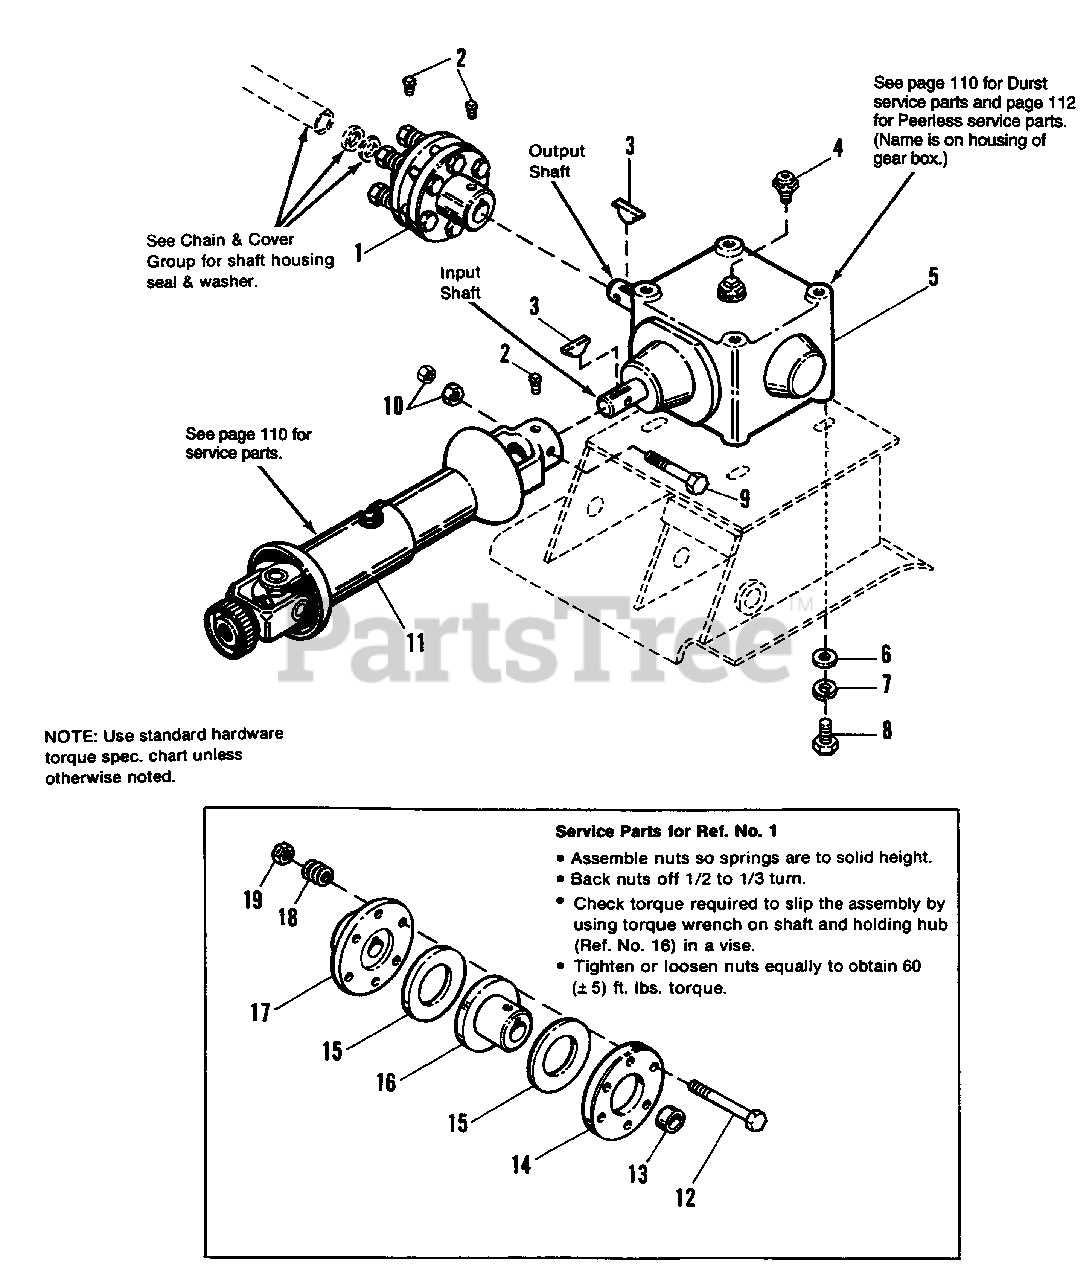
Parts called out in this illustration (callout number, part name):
1	TORQUE LIMITER ASSY.
2	SETSCREW, 5/16-18 x 3/4
3	KEY, Hi-Pro, 1/4 x 7/8
4	PLUG, Vent, 1/8-27 NPT
5	DRIVE ASSY., Right Angle
6	WASHER, Flat, 3/8 Std.
7	WASHER, Lock, 3/8
8	CAPSCREW, Hex Hd., 3/8-16 x 3/4
9	CAPSCREW, Hex Hd., 1/4-20 x 3
10	NUT, Hexlock, 1/4-20
11	DRIVESHAFT ASSY.
12	CAPSCREW, Hex Hd., 5/16-18 x 2-3/4
14	PLATE, Clutch
15	DISC, Clutch
16	HUB ASSY.
17	HUB, Clutch
19	NUT, Hex, Centerlock 5/16-18
